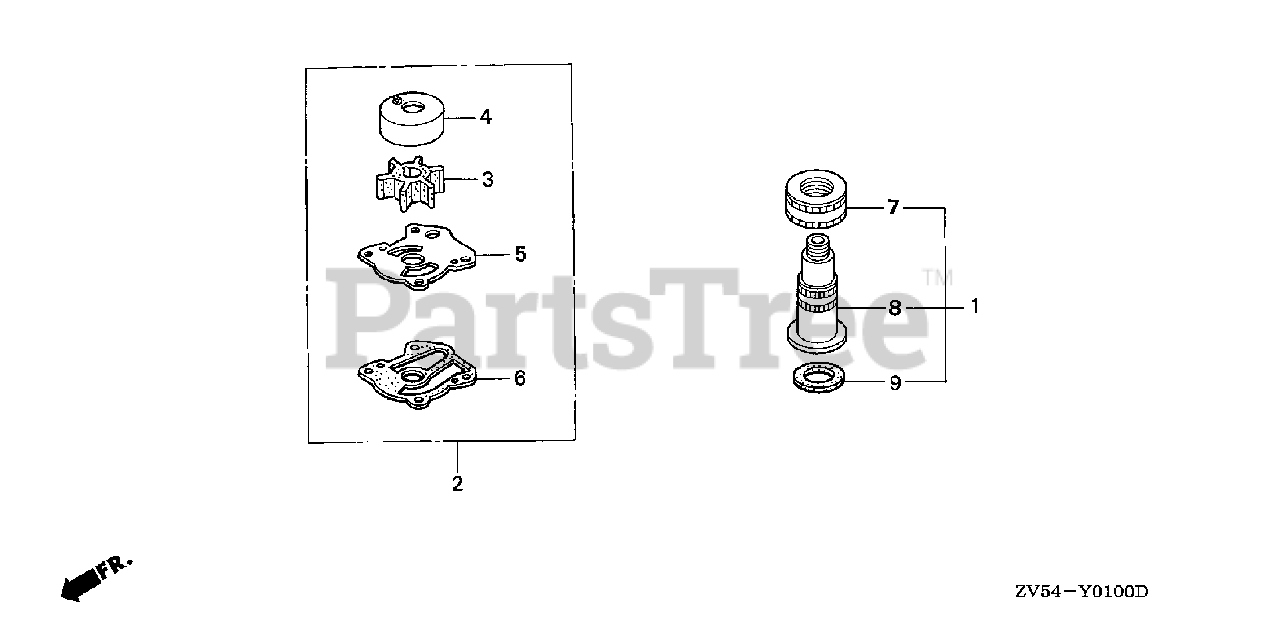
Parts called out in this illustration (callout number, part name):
1	JOINT KIT, WATER HOSE
2	IMPELLER KIT, PUMP
2	PUMP KIT, IMPELLER
3	IMPELLER, PUMP
4	LINER, PUMP
5	COVER, IMPELLER
6	GASKET B, IMPELLER
7	NUT, WATER MOUTH
8	JOINT, WATER HOSE
9	SEAT, WATER MOUTH
